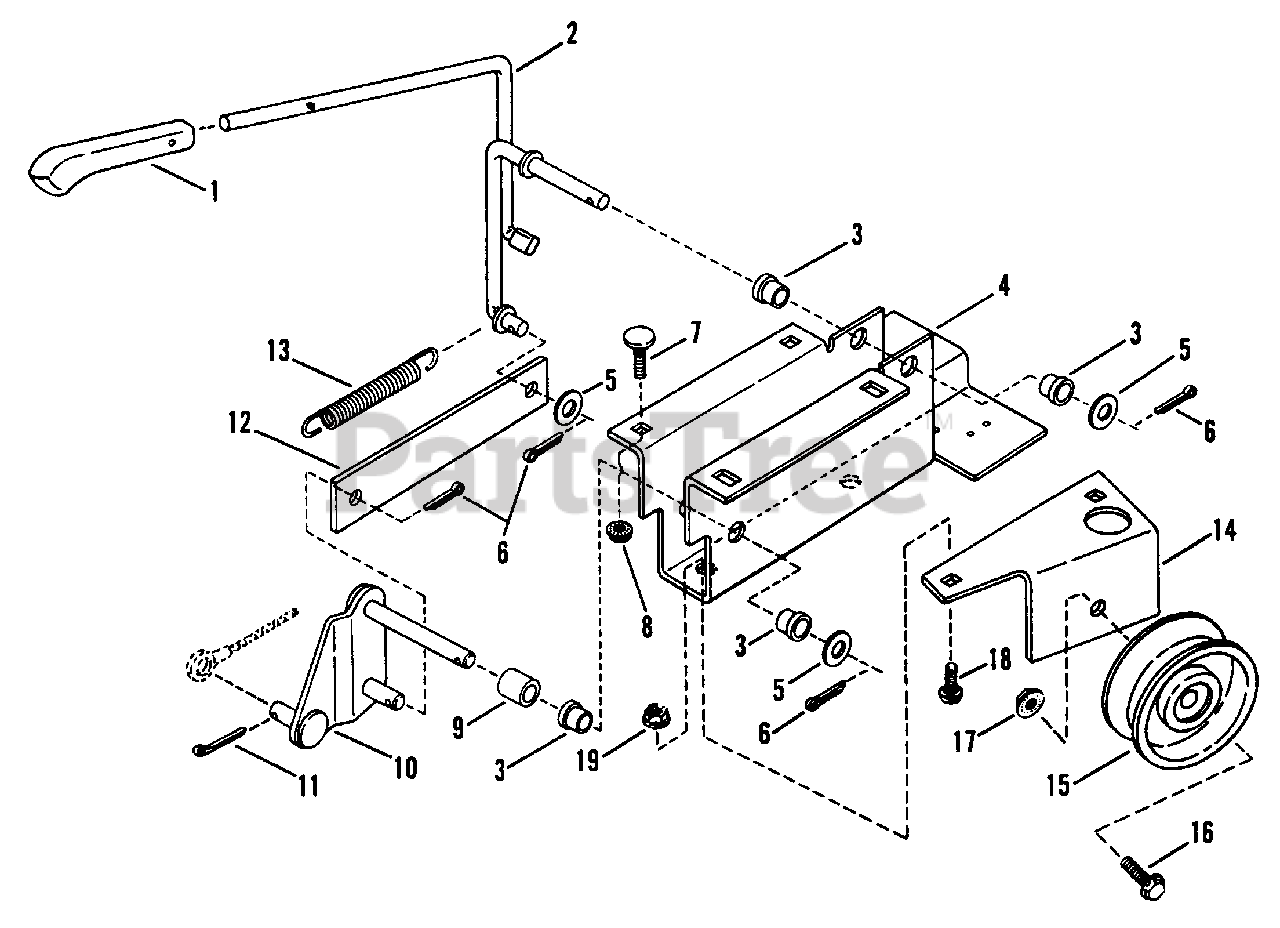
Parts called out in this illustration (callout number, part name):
1	KNOB, Handle 7/16"
2	HANDLE, Blade Engagement (No longer available)
3	BUSHING
4	BRACKET, Handle
5	WASHER, 3/8 SAE YZ
6	COTTER-PIN, 3/32 x 3/4"
7	BOLT, 1/4-20 x 5/8 Flat Hd. Carriage
8	NUT, 1/4-20 Hex Flange Lock
9	SPACER .625 OD x .380 ID x .560 L
10	PIVOT ARM ASSEMBLY
11	COTTER-PIN, 3/32 x 1"
13	SPRING, Return
14	BRACKET, Idler Support
15	PULLEY, Idler 2.75" OD
16	BOLT, 3/8-16 x 1 3/4" Hex Flange Lock
17	NUT, 3/8-16 Hex Lock
18	BOLT, 5/16-18 x 1/2" Short Neck Carr.
19	NUT, 5/16-18 Hex Lock Flanged
